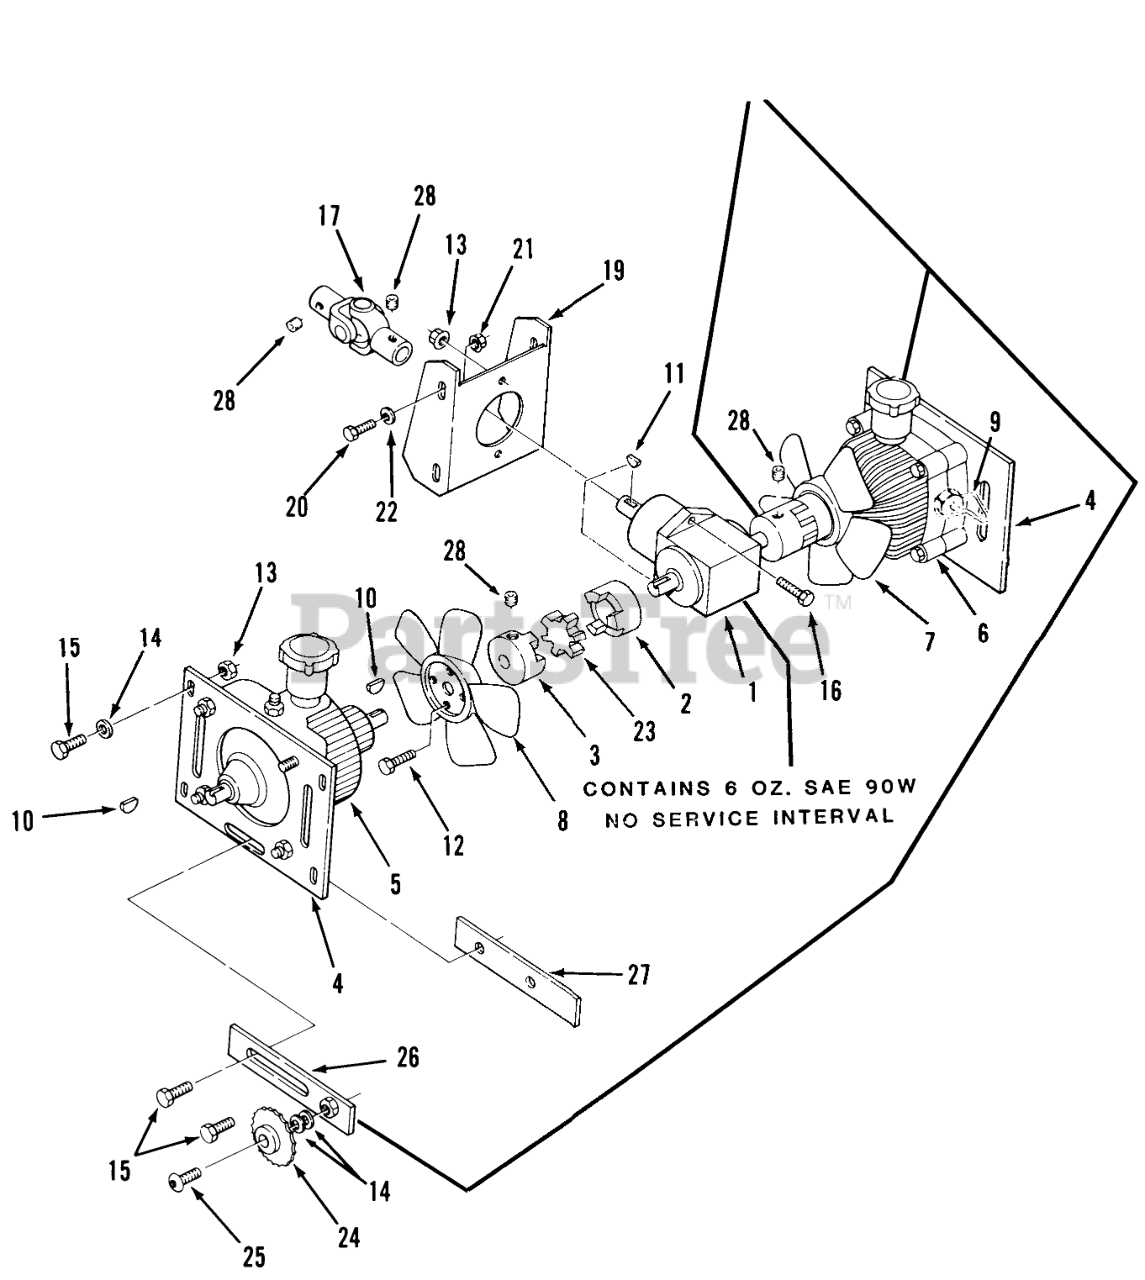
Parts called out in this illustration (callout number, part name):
1	"T" Gear Box (Peerless 1000)
2	LJ Coupler (.875 x 3/16 Keyway)
3	LJ Coupler (.670 X 1/8 Keyway)
4	Hydro Mounting Plate
5	Hydrostatic Transmission (counterclockwise rotation input shaft)
6	Hydrostatic Transmission (clockwise rotation input shaft)
7	Fan LH
8	Fan RH
9	Dump Valve Clip
10	KEY WOODR 1/8X1/2 DI
11	KEY-WOODRUFF
12	Self Tapping Screw #10-24 x 1/2
13	NUT
14	Washer
15	BOLT
16	Bolt
17	U-Joint (includes Shaft Adapter, Spirol Pin, Wire Keeper and Set Screws)
19	GEAR BOX BRKT 20104K
20	Bolt
21	Flanged Nut
22	WASHER 5/16 SAE
23	Coupling Spider
24	IDLER SPROCKET 20288
25	Idler Sprocket Bolt
26	ASSY-CHAIN TENSIO B
27	Back-up Plate
28	Set Screw
